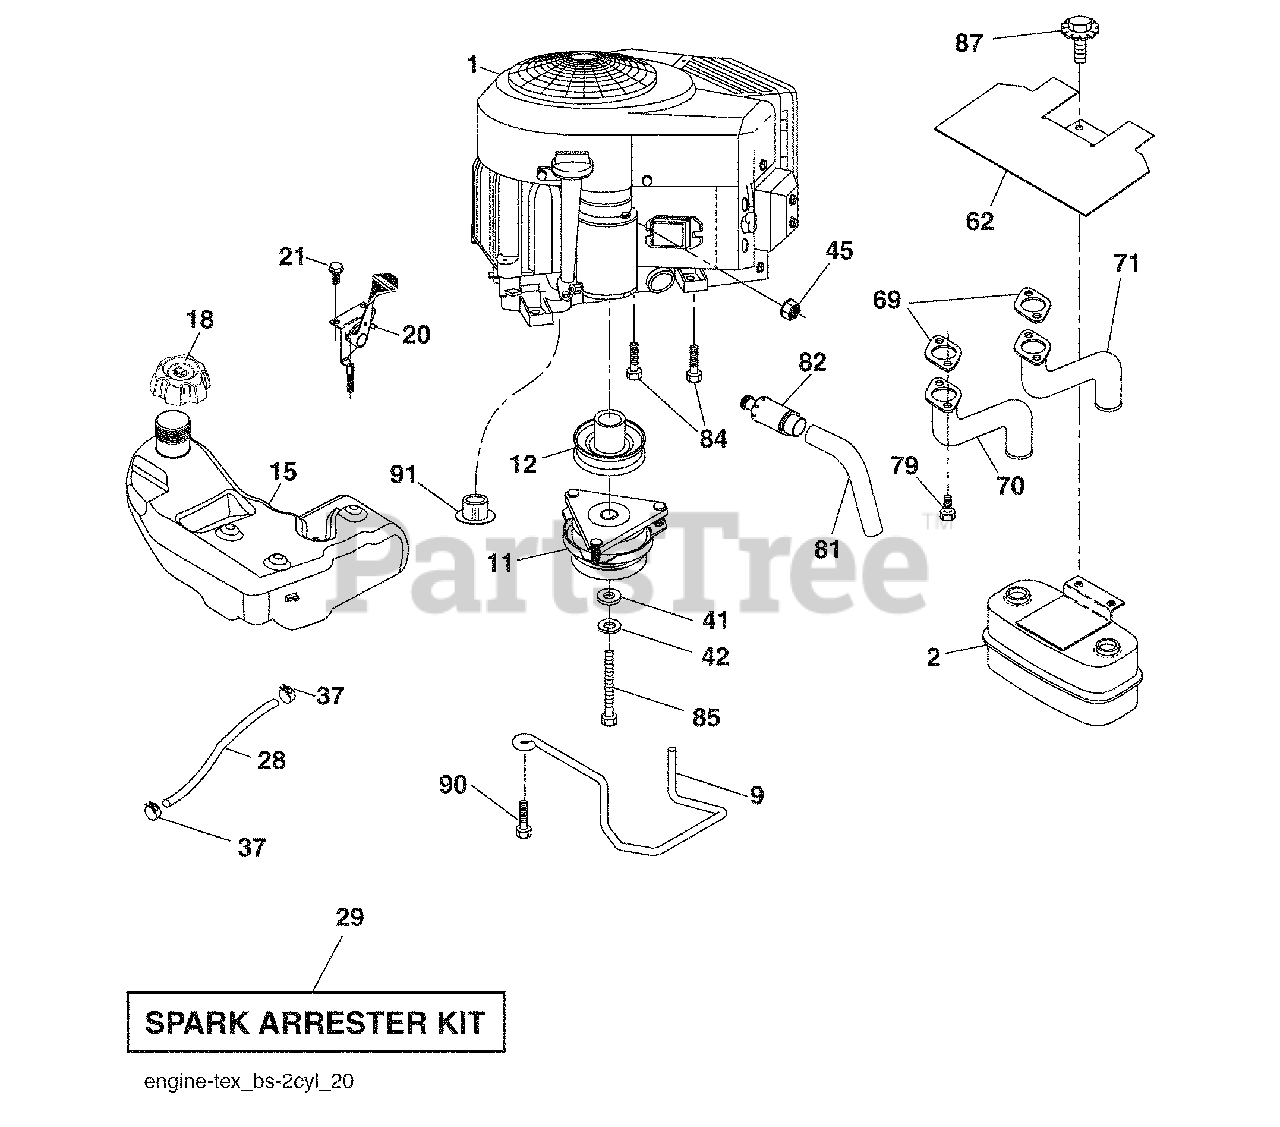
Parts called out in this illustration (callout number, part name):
9	Keeper Belt Engine
11	Clutch Electric
12	Pulley Engine
15	Tank Fuel 4.0
18	Cap Asm
20	Control Throttle
21	Screw #10 x 0.750
28	Fuel Line
29	Spark Arrester Kit
37	Clamp Hose
41	Washer 1-1/2 OD x 15/32 ID x .250
42	Washer Lock 7/16
45	Nut Keps Hex 1/4-20 unc
62	Shield Heat Muffler
70	Tube Exhaust LH
71	Tube Exhaust RH
79	Screw Socket Head 5/16-18 x 1
81	Tube Drain Oil Easy
82	Plug Drain Oil Easy
84	Screw 3/8-16 x 1-1/4
85	Bolt Hex 7/16-20 x 3.75 Gr. 5
87	Bolt 5/16-18 unc x 1 w/Sems
90	Screw 3/8-16 x 1
